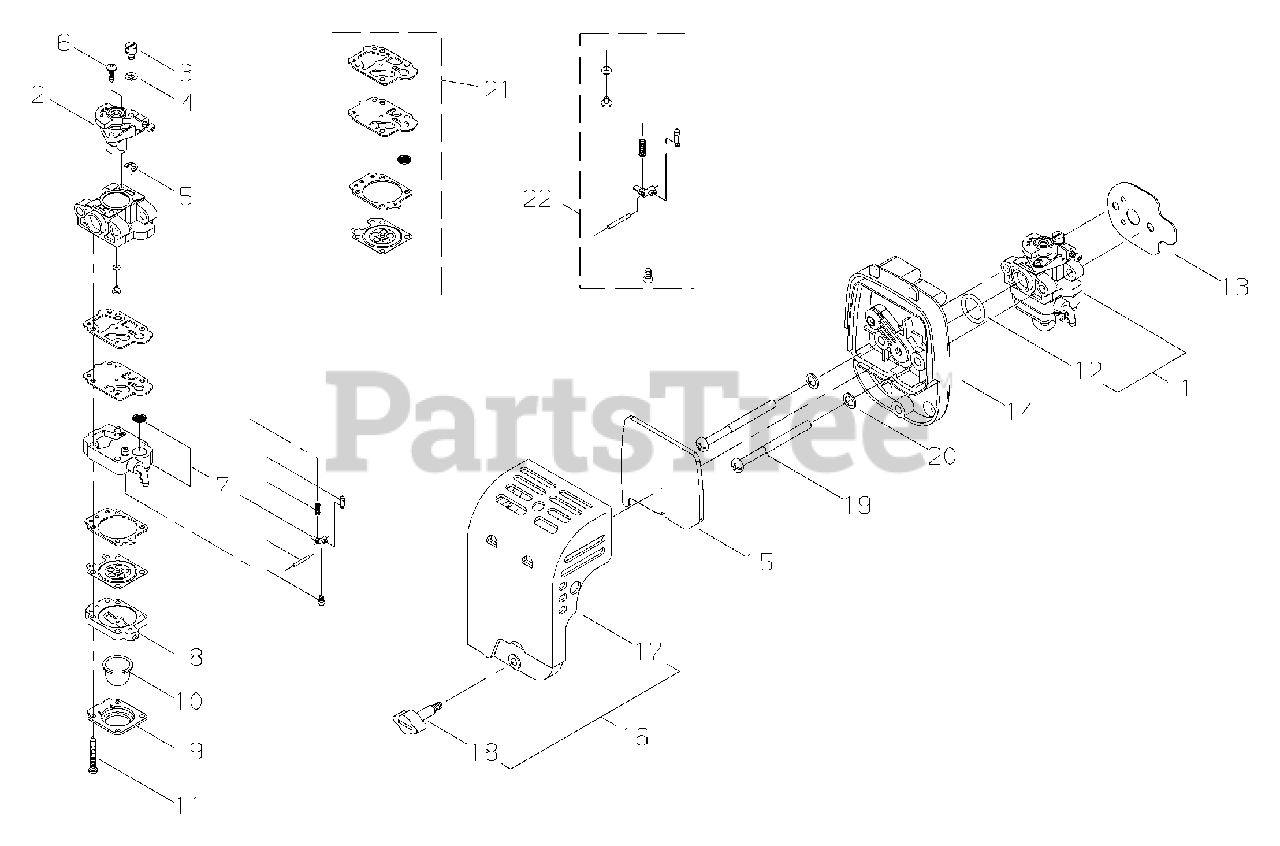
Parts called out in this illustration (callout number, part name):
1	CARBURETOR
2	VALVE ASSY, THROTTLE
3	SWIVEL
4	WASHER
5	E-RING
6	SCREW, THROTTLE COLLAR
7	BODY ASSY, PUMP
8	BODY ASSY, PURGE
9	RETAINER, PURGE BULB
10	BULB, PURGE
11	SCREW
12	O-RING 15
13	GASKET, INTAKE
14	CASE ASSY, AIR FILTER
15	FILTER, AIR
16	COVER ASSY, AIR FILTER
17	COVER, AIR FILTER
18	THUMBSCREW M5
19	SCREW M5×60
20	WASHER 5 MM
21	GASKET / DIAPHRAGM KIT
22	VALVE KIT, INLET NEEDLE
